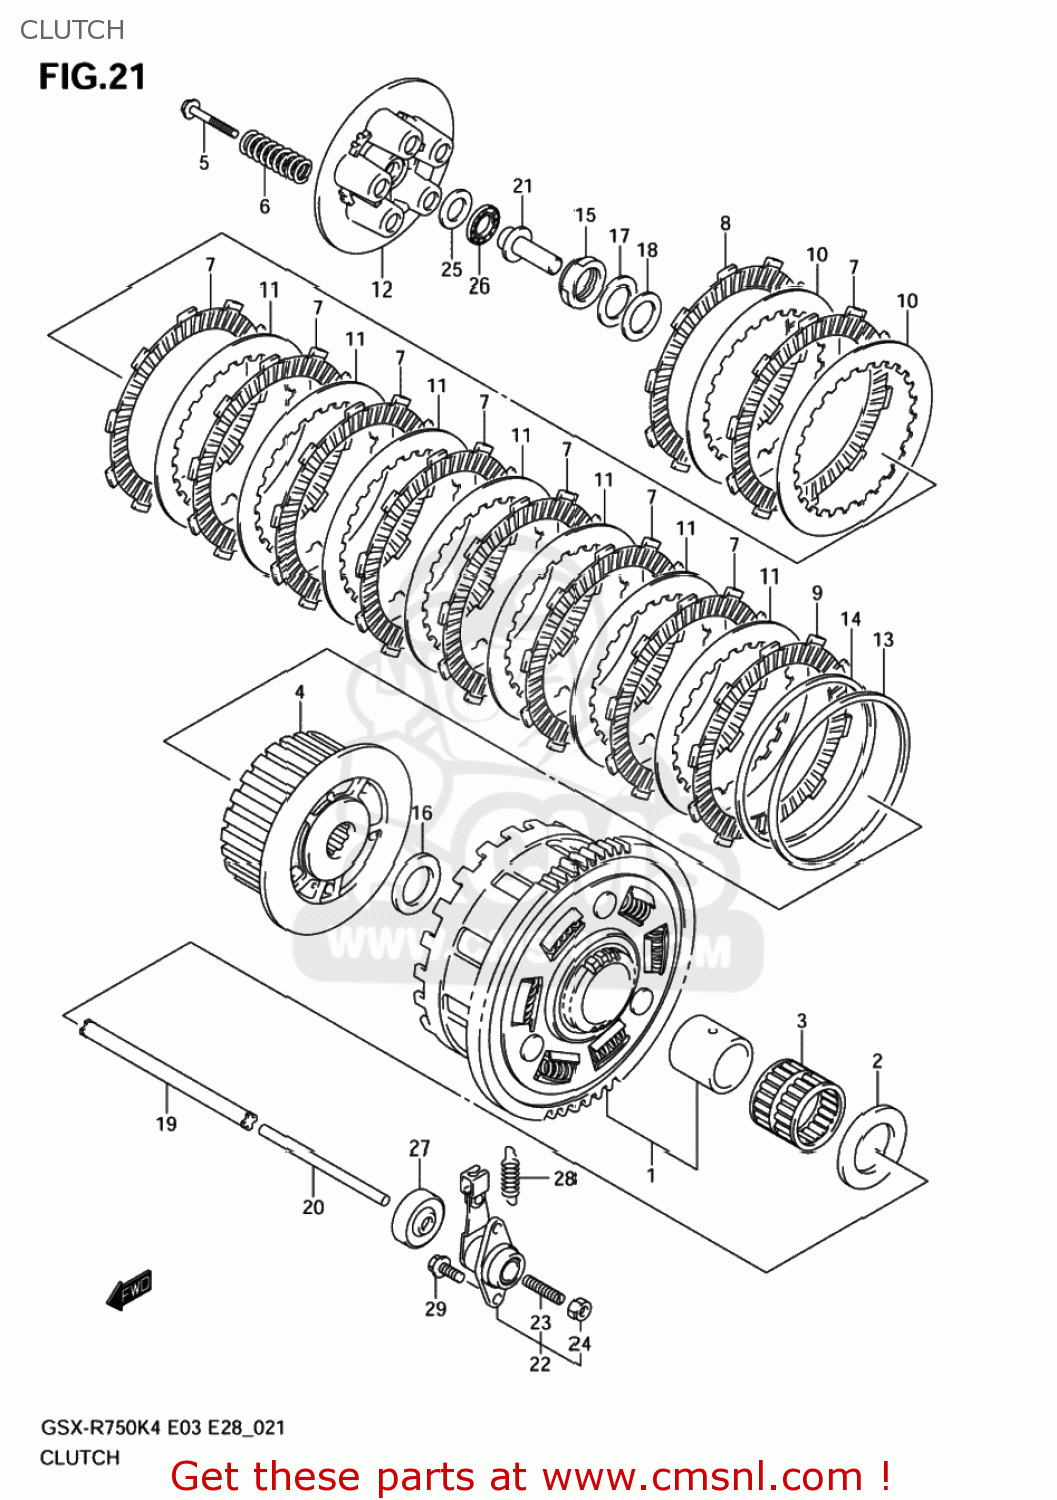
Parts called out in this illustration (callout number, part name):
1	GEAR ASSY,PRIM
2	WASHER(25X54X2.4)
3	BEARING(35X40X29.8)
4	HUB,CLUTCH SLEEVE
5	BOLT,CLUTCH SPRING
6	SPRING,CLUTCH
7	PLATE,CLUTCH DRIVE NO.1 (NAS)
8	PLATE,CLUTCH DRIVE (NAS)
9	PLATE,CLUTCH DRIVE (NAS)
10	PLATE,CLUTCH DRIVEN NO.1
11	PLATE,CLUTCH DRIVEN NO.2
12	DISC,CLUTCH PRESSURE
13	SEAT,CLUTCH PLATE WAVE WASHER
14	WASHER,CLUTCH PLATE WAVE
15	NUT
16	WASHER(25X50X2.5)
17	WASHER
18	SHIM(25X38X1)
19	ROD,CLUTCH
20	ROD,CLUTCH PUSH,L
21	PIECE,CLUTCH PUSH
22	SCREW ASSY,CLUTCH RELEASE
23	SCREW(6X25)
24	NUT
25	WASHER(15.5X28X1)
26	BEARING(15X28X2)
27	SEAL,OIL(6X34X10)
28	SPRING
29	BOLT
